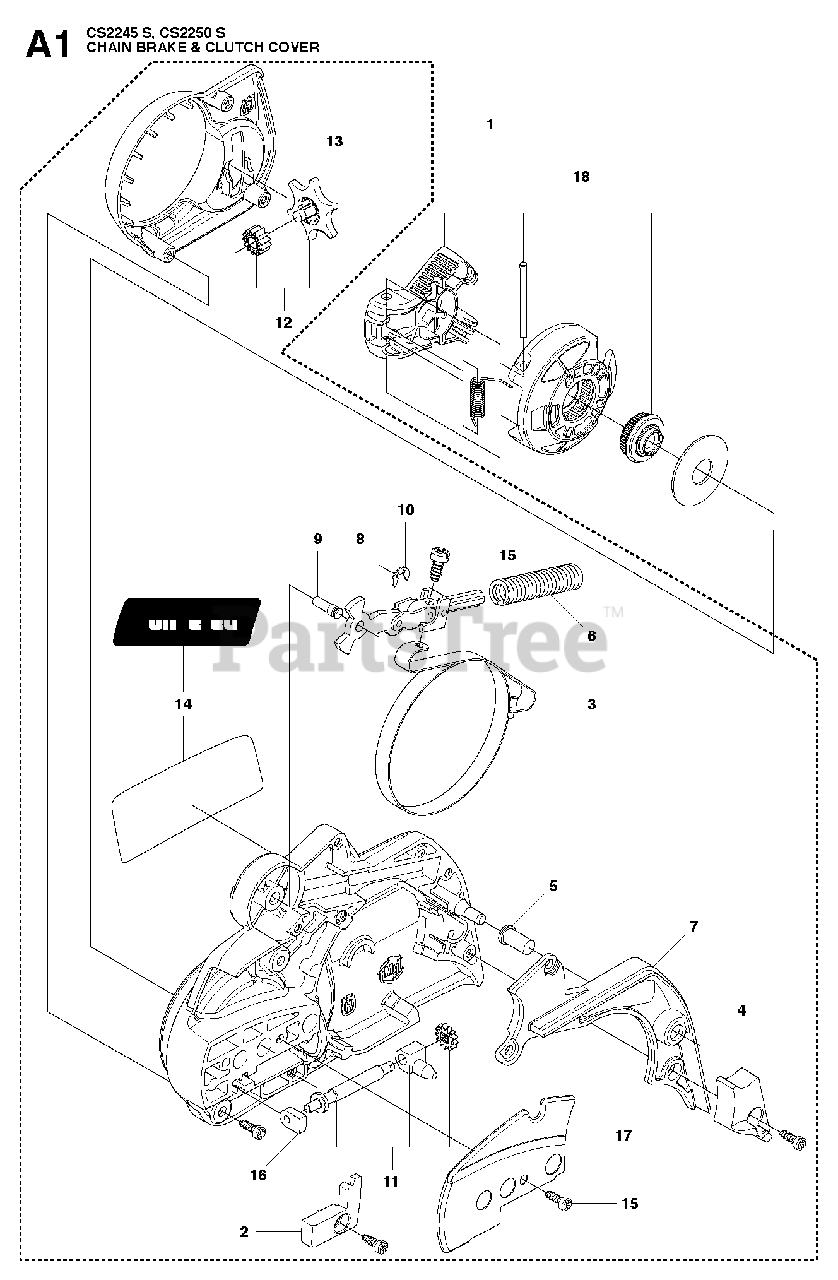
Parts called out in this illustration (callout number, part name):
1	CLUTCH COVER ASSY
2	COVER
3	BRAKE BAND
4	WEAR GUARD, CHAIN
5	SLEEVE
6	SPRING
7	COVER, CHAIN BRAKE
8	JOINT
9	PIN
10	E-RING 4
11	CHAIN TENSIONER SCREW, COMP.
12	CHAIN TENSIONER WHEEL
14	LABEL
15	SCREW
16	BEARING SLEEVE
17	PLATE
